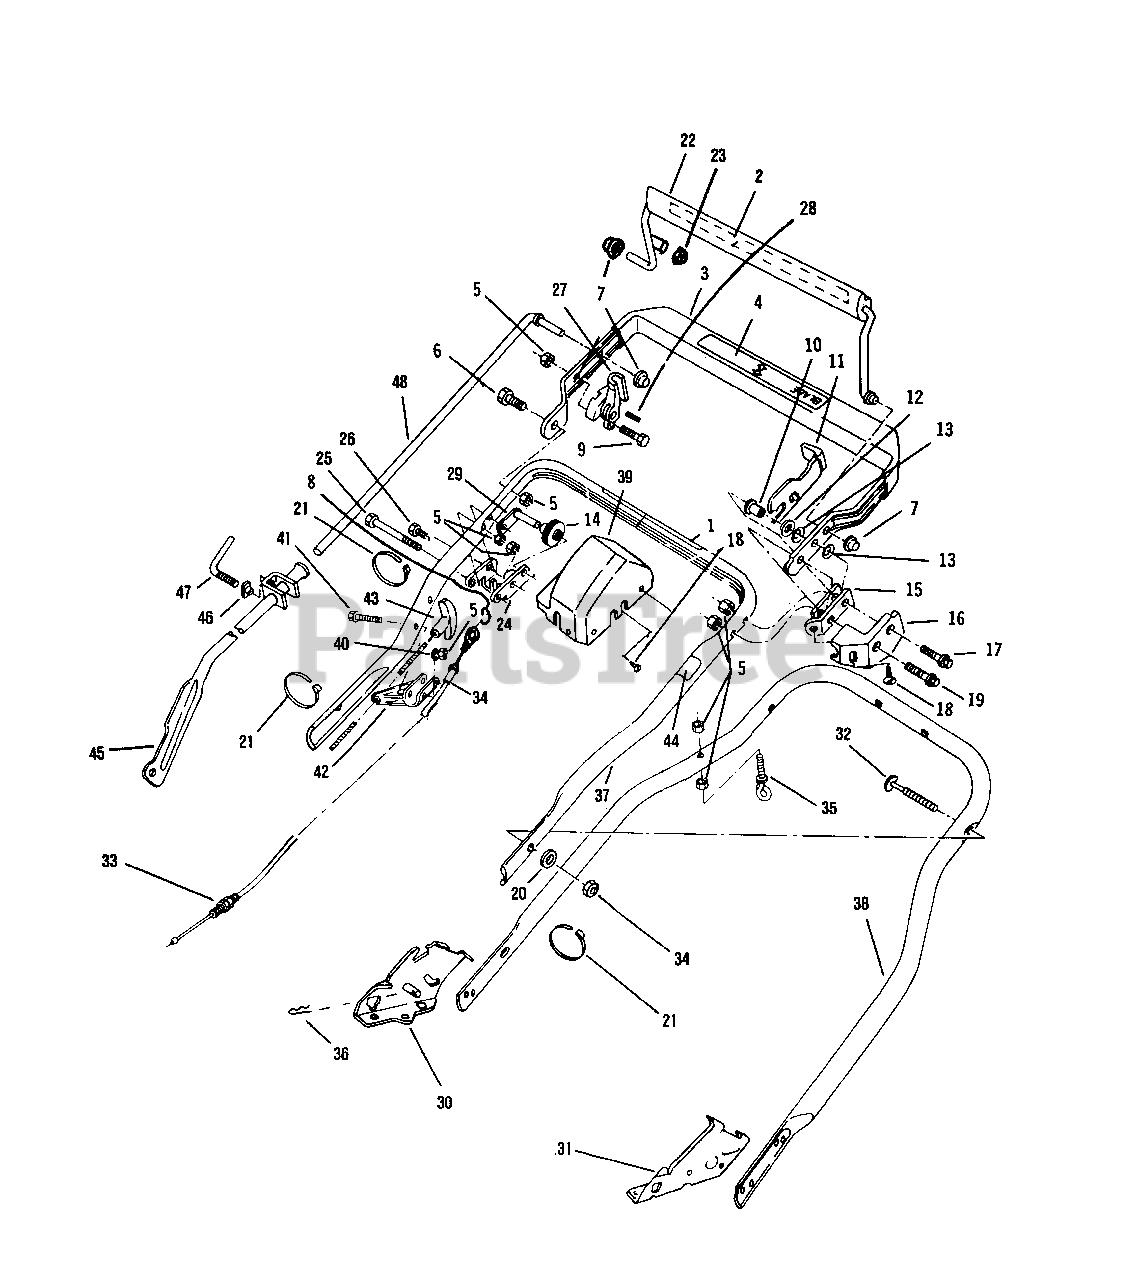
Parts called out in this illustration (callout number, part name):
1	Decal-Blade Control
2	Decal-Engine/Blade Control
3	Top Handle and Doubler Assem.
4	Decal-Drive Control
5	Locknut
6	Bolt-Shoulder-R.H.
7	Pushnut
8	Retaining Ring-Cable
9	Hex-Washer Head Shoulder Bolt
10	Spacer-Flanged
11	Lever-Lockout
12	Washer-Plain
13	Washer-Spring
14	Pulley
15	Down Stop
16	Guard-Lockout
17	Bolt-Shoulder
18	Screw-"Tapite"
19	Bolt-Shoulder-L.H.
20	Washer
21	Tie Strap
22	Control Lever and Nut Assem.
23	Nut-Acorn
24	Bracket-Clutch Cable
25	Screw
26	Screw-Clutch Cable Brk't.
27	Cam and Roll Pin Assem.
28	Roll Pin
29	Pivot-Bracket-Pulley
30	Handle Bracket-R.H.
31	Handle Bracket-L.H.
32	Screw
33	Control Cable Assem.
34	Nut
35	Eyebolt
36	Hair Pin-Handle Brk't.
37	Handle Section-Center
38	Handle Section-Bottom
39	Cover
40	Washer-Plain
41	Screw-Truss Head
42	Rope Guide Assembly
43	Handle-Starter
44	Decal-Drive Lockout
45	Control Lever Assem.
46	Nut-Control Lever Clamp
47	Lever-Rod Clamp
48	Rod-Control
